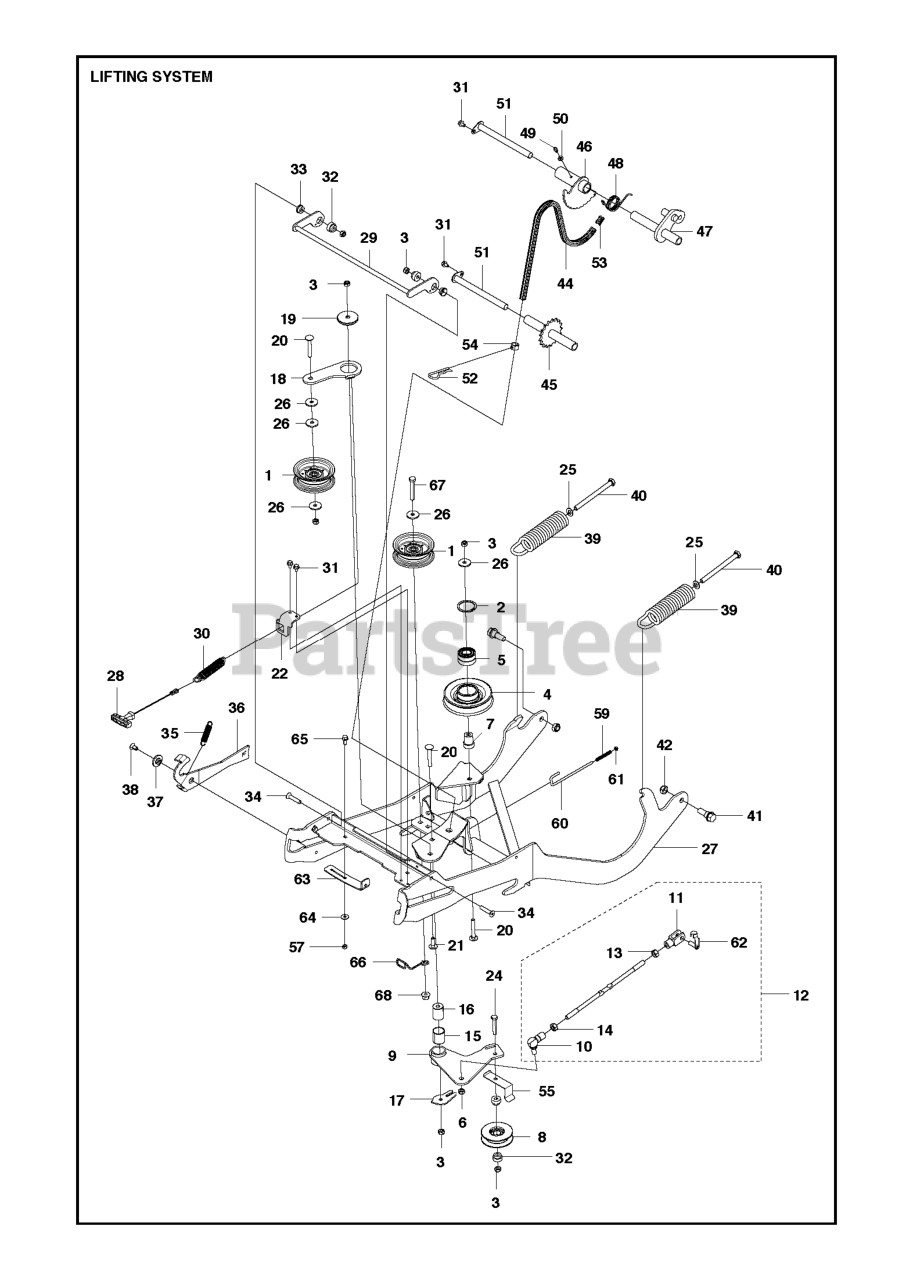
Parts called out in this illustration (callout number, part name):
2	RETAINING RING
3	LOCKNUT M8
5	BALL BEARING 6004-2RS1
6	NUT
11	RETAINER
15	BUSHING
24	SCREW
25	WASHER
38	BOLT REAR WHEEL
49	GREASE NIPPLE
50	WASHER - M6
57	LOCKNUT M6
61	LOCKNUT M5
64	WASHER - 26X6.5X1.6
65	Screw
68	NUT FLANGE
